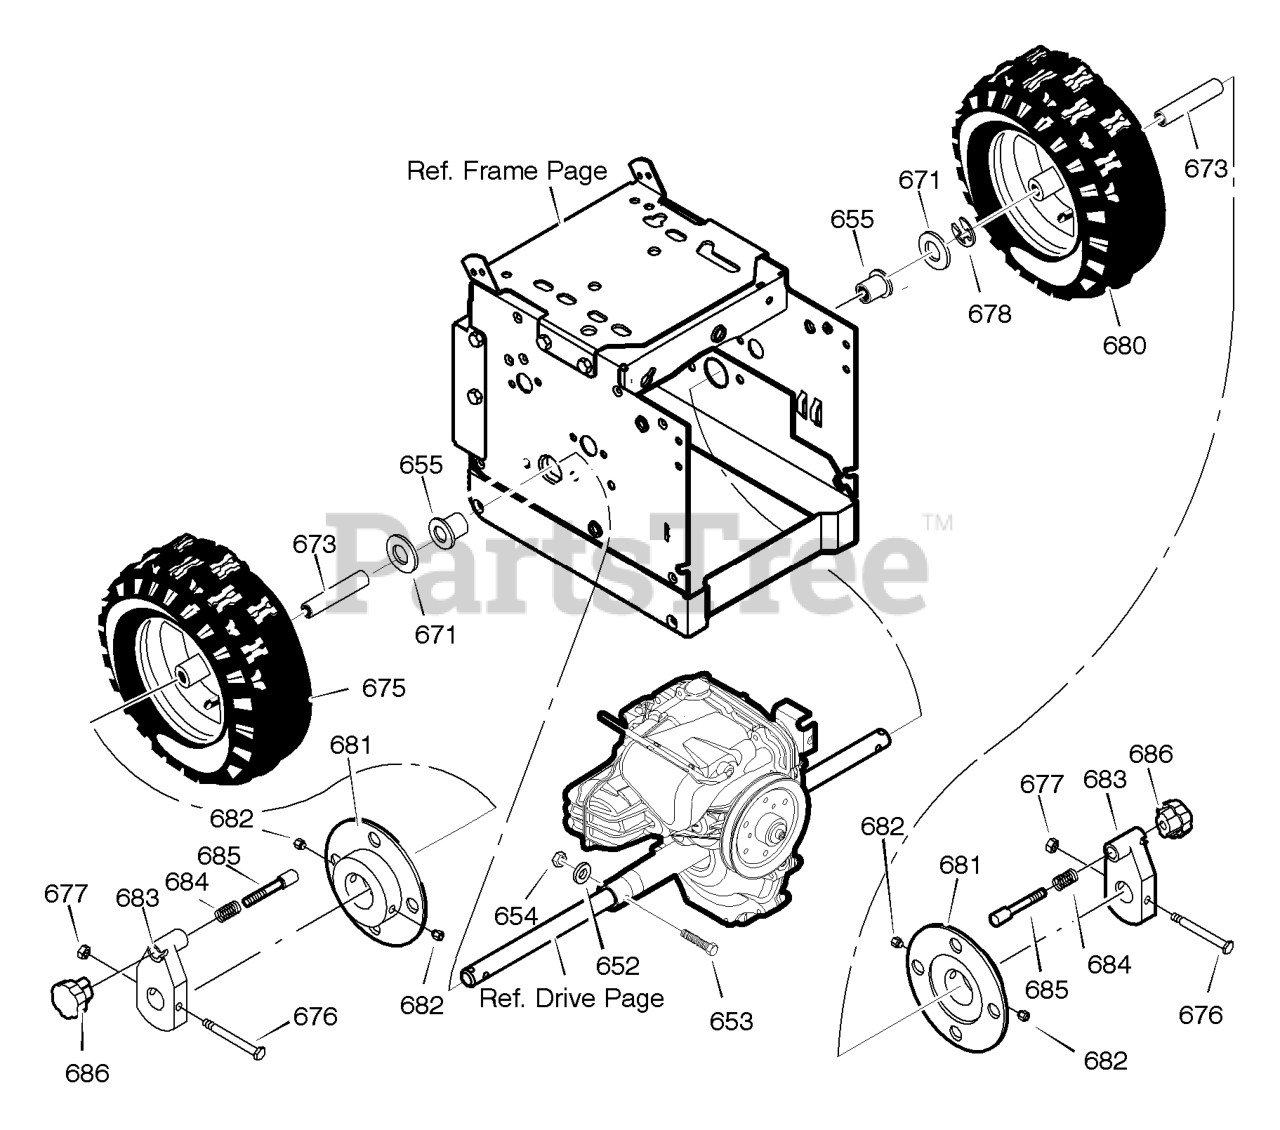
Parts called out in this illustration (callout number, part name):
652	SPACER
653	SCREW, 1/4-20X1.75
654	NUT, 1/4-20
655	BEARING, AXLE
671	FLATWASHER
673	BUSHING, WHEEL
675	TIRE & RIM, RIGHT
676	SCREW, 1/4-20X2.25
677	NUT, 1/4-20
678	RING, RET
680	TIRE & RIM, LEFT
681	DISC, WHEEL
683	HUB, WHEEL
684	SPRING
685	PIN, LOCK
686	KNOB
